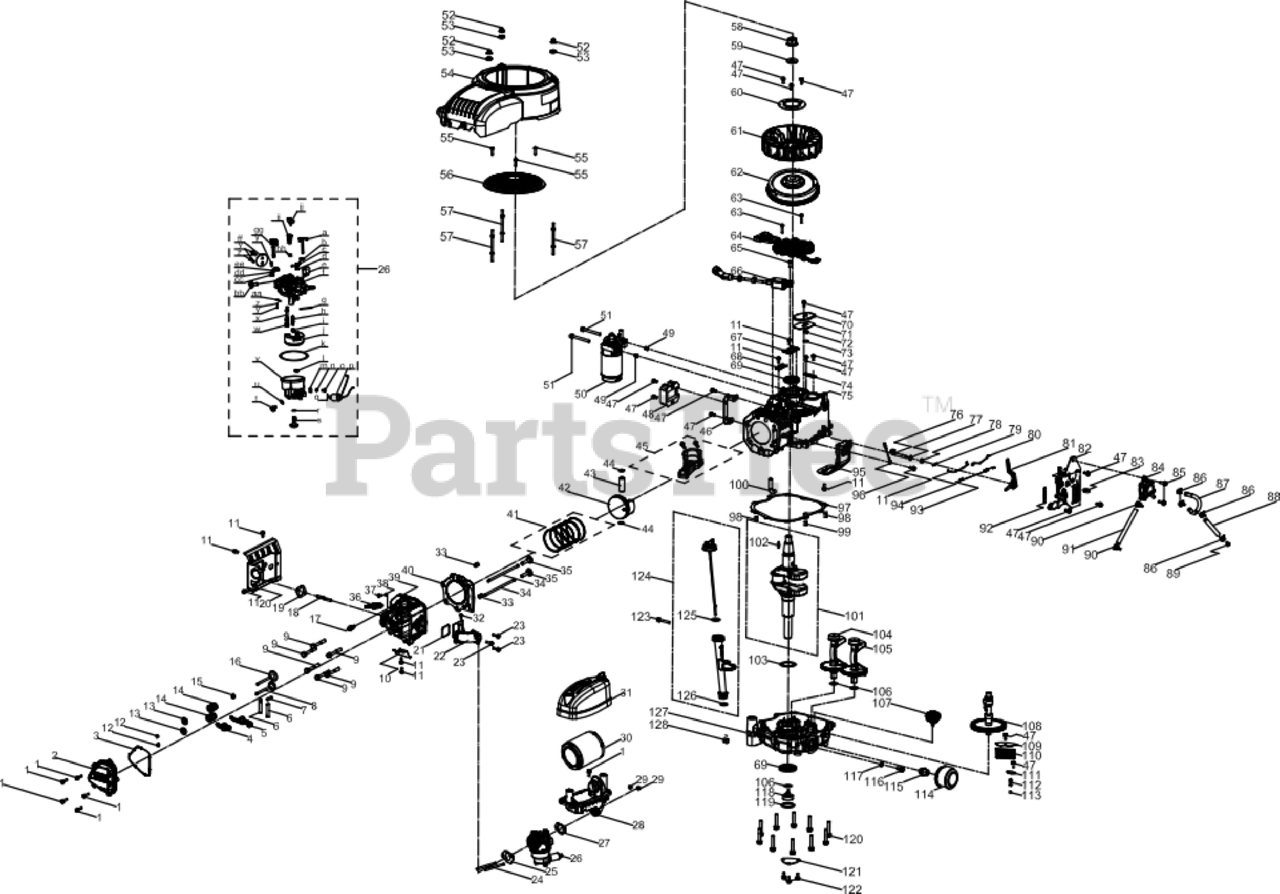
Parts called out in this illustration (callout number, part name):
1	Bolt, M6x25
2	Valve Cover
3	Gasket, Valve Cover
4	ROCKER ARM (EXHAUST)
5	ROCKER ARM (INTAKE)
6	Rocker Arm Coreshaft
7	Rocker Arm Pin
8	Exhaust Valve
9	Bolt, M10x1.25x70
11	Bolt, M6x12
12	Valve Locker
13	Valve Spring Seat
14	Valve Spring
15	Intake Valve Seal
16	Intake Vavle
19	Gasket, Muffler
20	Shroud, Left
21	Gasket, Intake Manifold
22	Intake Manifold
23	Bolt, M6x22
24	Stud, M6x92
25	Gasket, Carburetor
26	Carburetor
27	Gasket, Air Filter
28	Air Filter Base
30	Air Filter Element
31	Air Filter Cover
32	Self-tappling Screw, ST4.8x16
33	Pin, 12x16
36	Spark Plug
37	Bolt, M5x10
38	Washer, 5.3x1x10
39	Cylinder Head
40	Gasket, Cylinder Head
41	Piston Ring Set
43	Piston Pin
44	Circlip
45	Connecting Rod Assembly
46	Regulator Bracket Assembly
47	Bolt, M6x14
49	Pin, 10x12
50	Electric Starter
51	Bolt, M8x80
52	Nut,M6
55	Self-tappling Screw, ST5.5x25
58	Nut, M20x1.5
59	Washer, 20.5x5x40
60	Cooling Fan Plate
61	Cooling Fan
62	FLYWHEEL
63	Bolt, M5x28
64	CHARGING COIL
65	Bolt, M6x28
66	Ignition Module
67	Wire Board
68	Wire Board
69	Oil Seal, 38x58x8
70	Breather Cover
71	Gasket, Breather Cover
72	One-way Vavle Spring
73	Breather Valve
76	Governor Gear Shaft
77	Washer, 8x0.8x16
78	Oil Seal, 8x14x4
79	Cotter Pin
80	Choke Lever
81	Governor Lever
82	Governor Gear Bracket Assembly
83	Clip
84	Fuel Pump
85	Bolt, M6x18
86	Clamp
87	Breather Hose
88	Fuel Hose, 6.3x12.5x100
91	Fuel Hose, 6.3x12.5x180
92	Governor Spring
93	Idle Spring
94	Throttle Linkage
95	Shroud, Right
96	Earth Wire
97	Gasket, Crankcase
98	Pin, 9x14
99	Pin, 7x14
100	Breather Hose
101	Crankshaft
102	Woodruff Key
103	Washer, 38.3x1x54
104	Balance Shaft
105	Balance Shaft
106	Washer, 17.2x1x26
107	Governor Gear
109	Breather Cover
110	Breather Filter Screen
111	Breather Cover
113	Steel Ball, 8.731
114	Oil Filter
115	Connection Pipe
116	Bolt, M8x15
117	Washer, 8.3x1.5x17
119	Gasket, Oil Pump
120	Bolt, M8x45
121	Oil Pump Cover
122	Bolt, M6x12
123	Bolt, M6x45
124	Dipstick
125	O-Ring, Dipstick
126	O-Ring, Dipstick
127	Crankcase Cover
128	Earth Bolt
